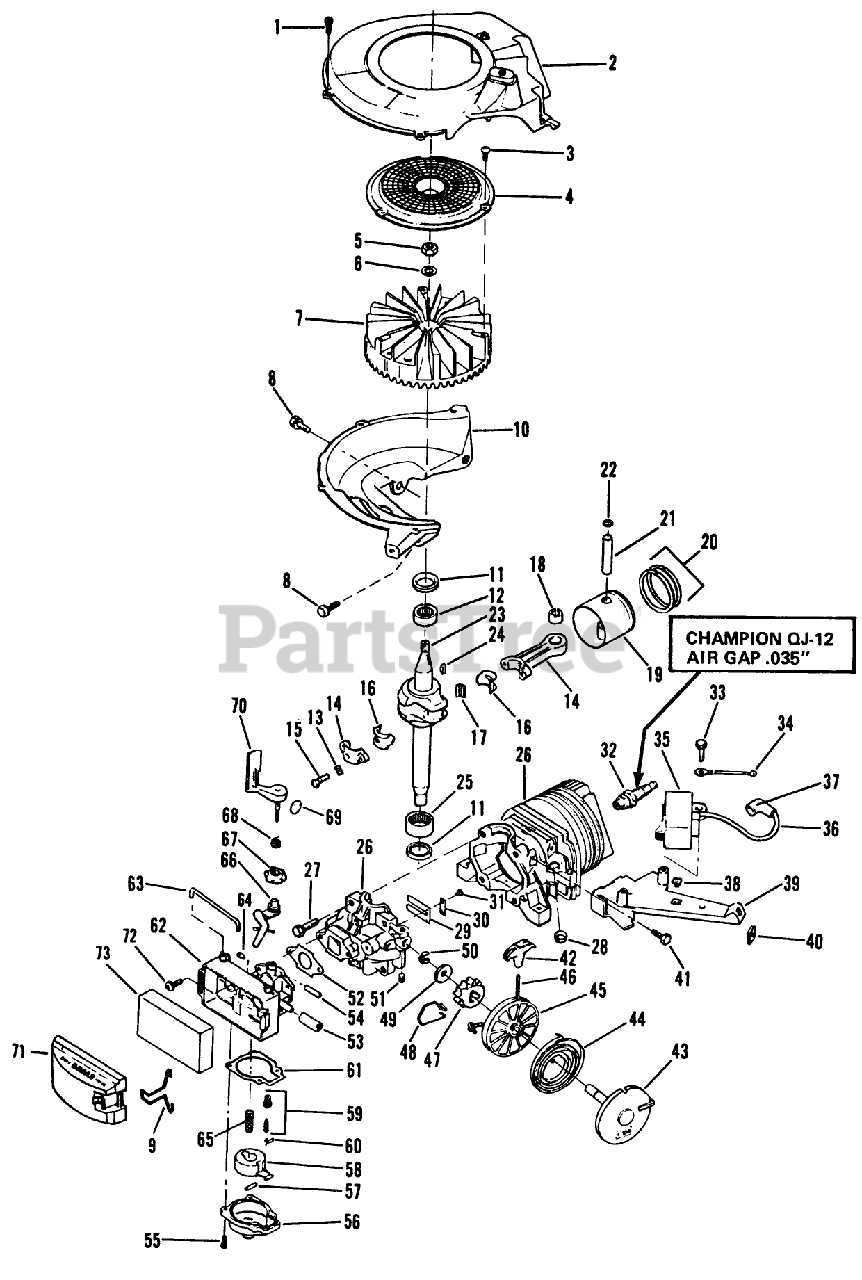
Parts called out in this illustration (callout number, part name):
1	SCREW S
2	AIR BAF&EYELET S
3	SCREW F
5	NUT
8	SCREW-SEMS
9	RETAINER-COVER, FILTER
12	BEARING V
15	SCREW
16	LINER ASM
18	BEARING AY F
22	RING-RETAINING
24	KEY
25	BEARING V
27	SCREW S
28	PLUG-CORE VF
30	PLATE-BACKUP, REED
36	HT LEAD&COVER XEV
38	NUT-CLIP
40	NUT - SPEED S
42	HANDLE STARTER S
44	SPRING S
48	SPRING F
49	WASHER S
51	SET SCREW
52	GASKET CARB S
54	TUBING PRIMER S
55	SCREW-HH
63	RETAINER
64	F-SCREW CARB
66	LEVER
67	ADJUSTMENT COLLAR
68	SPRING
69	DISC S
72	SCREW
